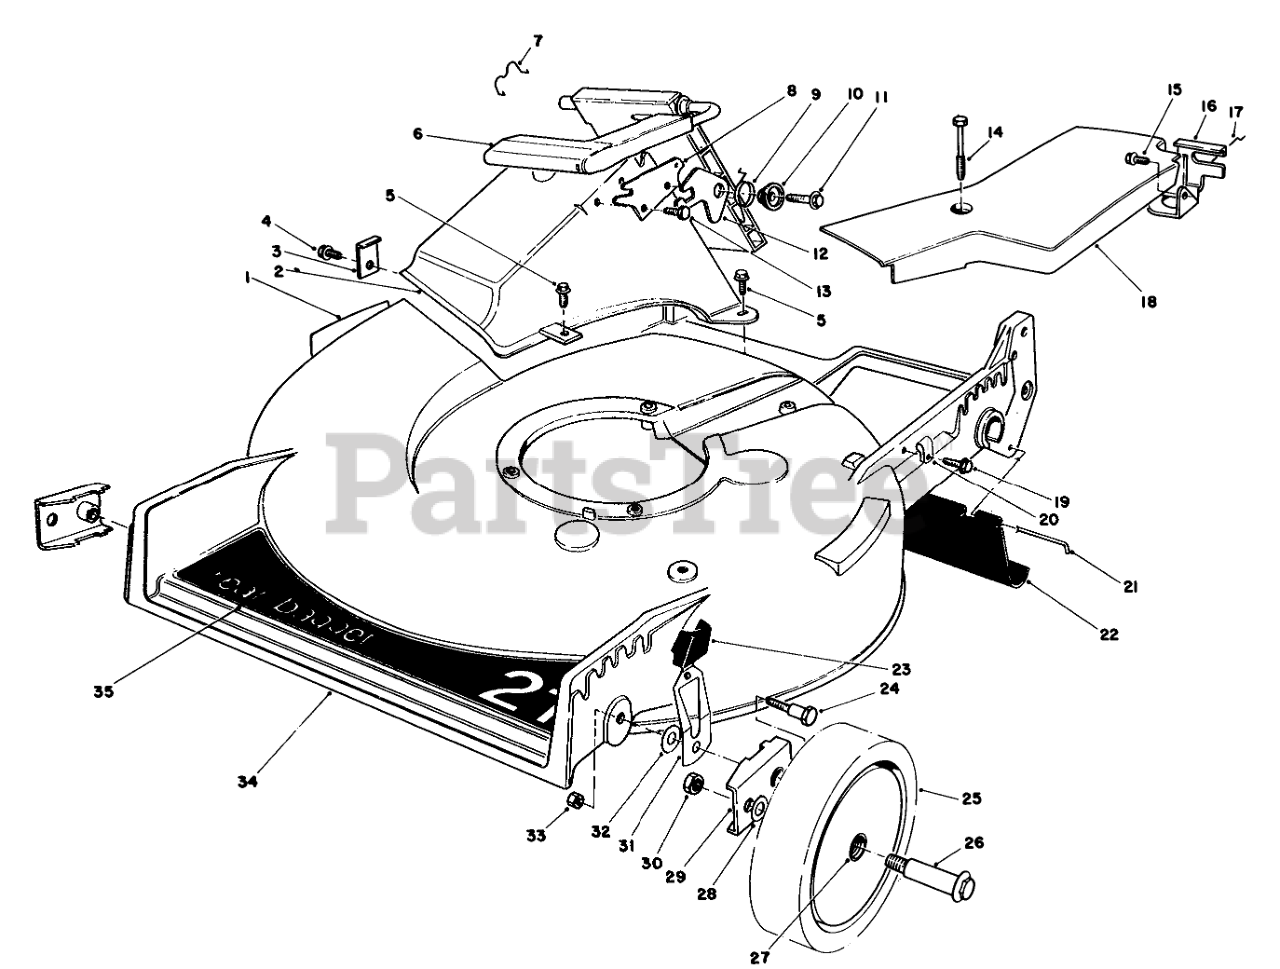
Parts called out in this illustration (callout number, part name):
1	DECAL-DANGER
2	SCREW
3	TUNNEL CLIP
4	Tunnel Discharge
5	SCREW-HWH
6	Discharge Door Assembly
7	DOOR RET SPRING
8	DOOR LATCH PLATE
9	TORSION SPRING
10	DOOR SPACER
11	SCREW-HWH
12	SAFETY LATCH
13	SCREW-PLASTITE
14	SCREW-HHFTF
15	SCREW-HWHTF
16	Bracket-Traction Adj.
17	RETAINER-CABLE
18	Cover-Belt
19	SCREW
20	CLAMP-CABLE
21	ROD-SHIELD
22	SHIELD-TRAILING
23	KNOB-ARM
24	PIVOT SCREW
25	Wheel & Tire Assembly (Incl. Ref. #27)
26	WHEEL BOLT
27	BUSHING
28	WASHER
29	HP PIVOT ARM ASM
30	NUT-LOCK
31	Spring Arm
32	WASHER-PIVOT
33	NUT-LOCK, NI
34	Housing (Incl. Ref. #1)
35	DECK DECAL
